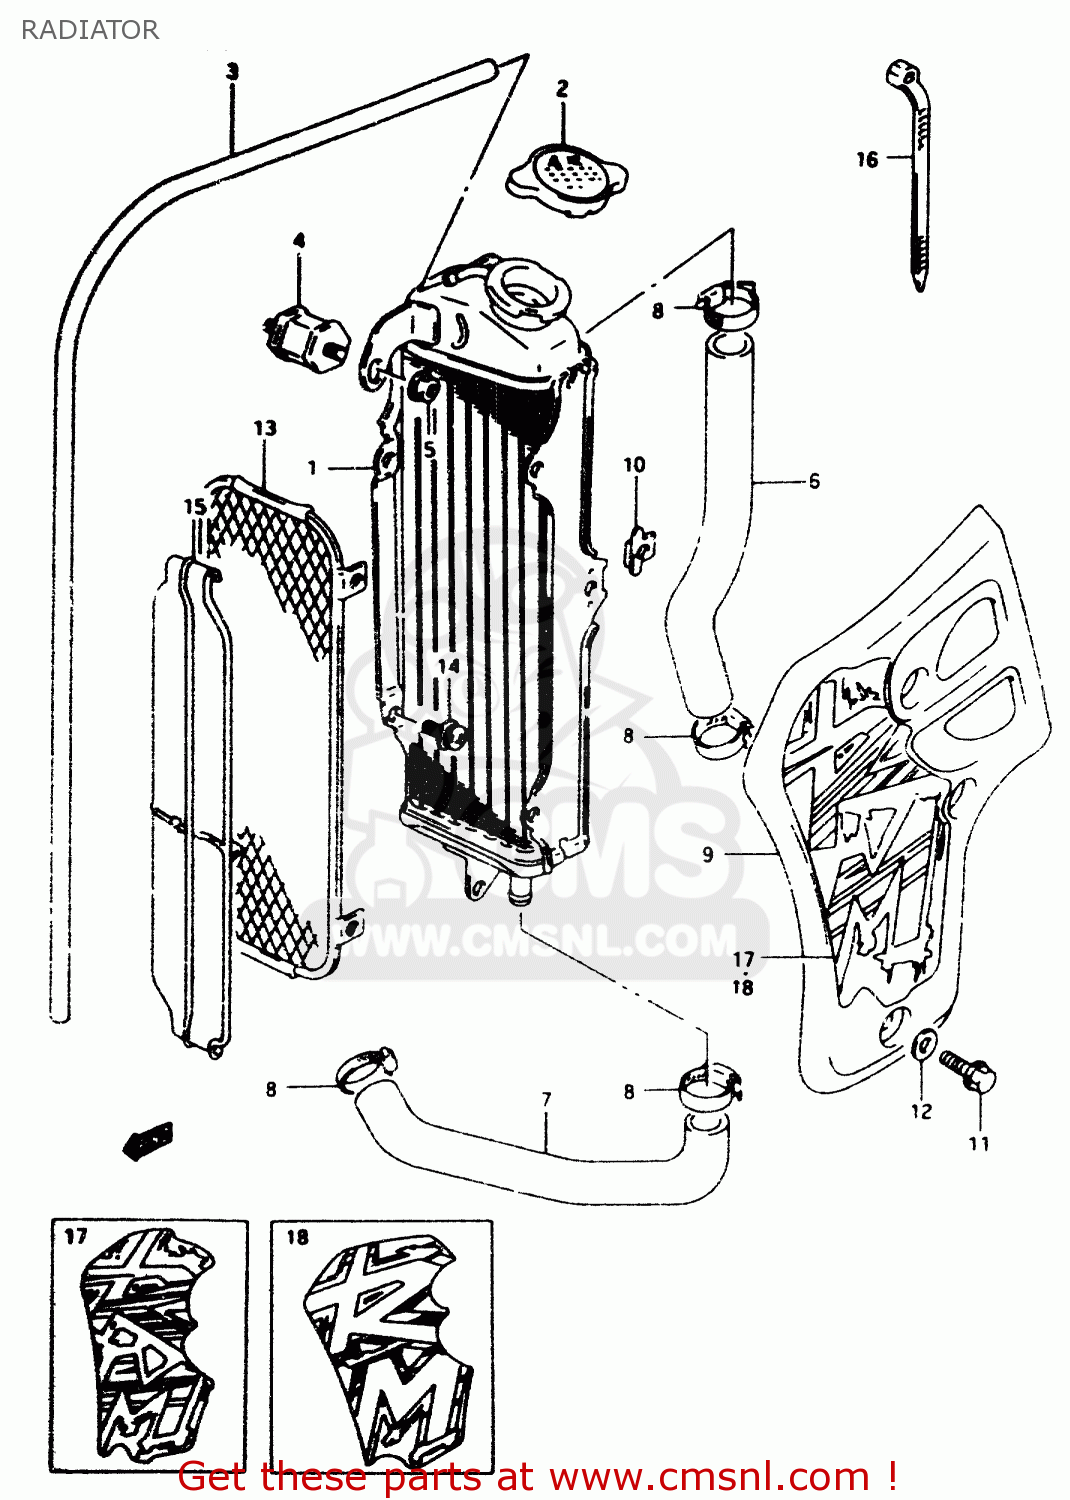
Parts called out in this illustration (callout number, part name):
1	RADIATOR COMP,WATER
2	CAP,RADIATOR
3	HOSE (5X8X600)
4	BOLT,RADIATOR CUSHION
5	NUT
6	HOSE,RADIATOR INLET
7	HOSE,RADIATOR OUTLET
8	CLAMP
9	COVER,RADIATOR (PURPLE)
10	PLATE,RADIATOR COVER FITING
11	BOLT
12	WASHER(6.5X18X1)
13	BUMPER,RADIATOR
14	SCREW
15	COVER,RADIATOR
16	CLAMP(L:235)
17	EMBLEM,RADIATOR COVER
18	EMBLEM,RADIATOR COVER
